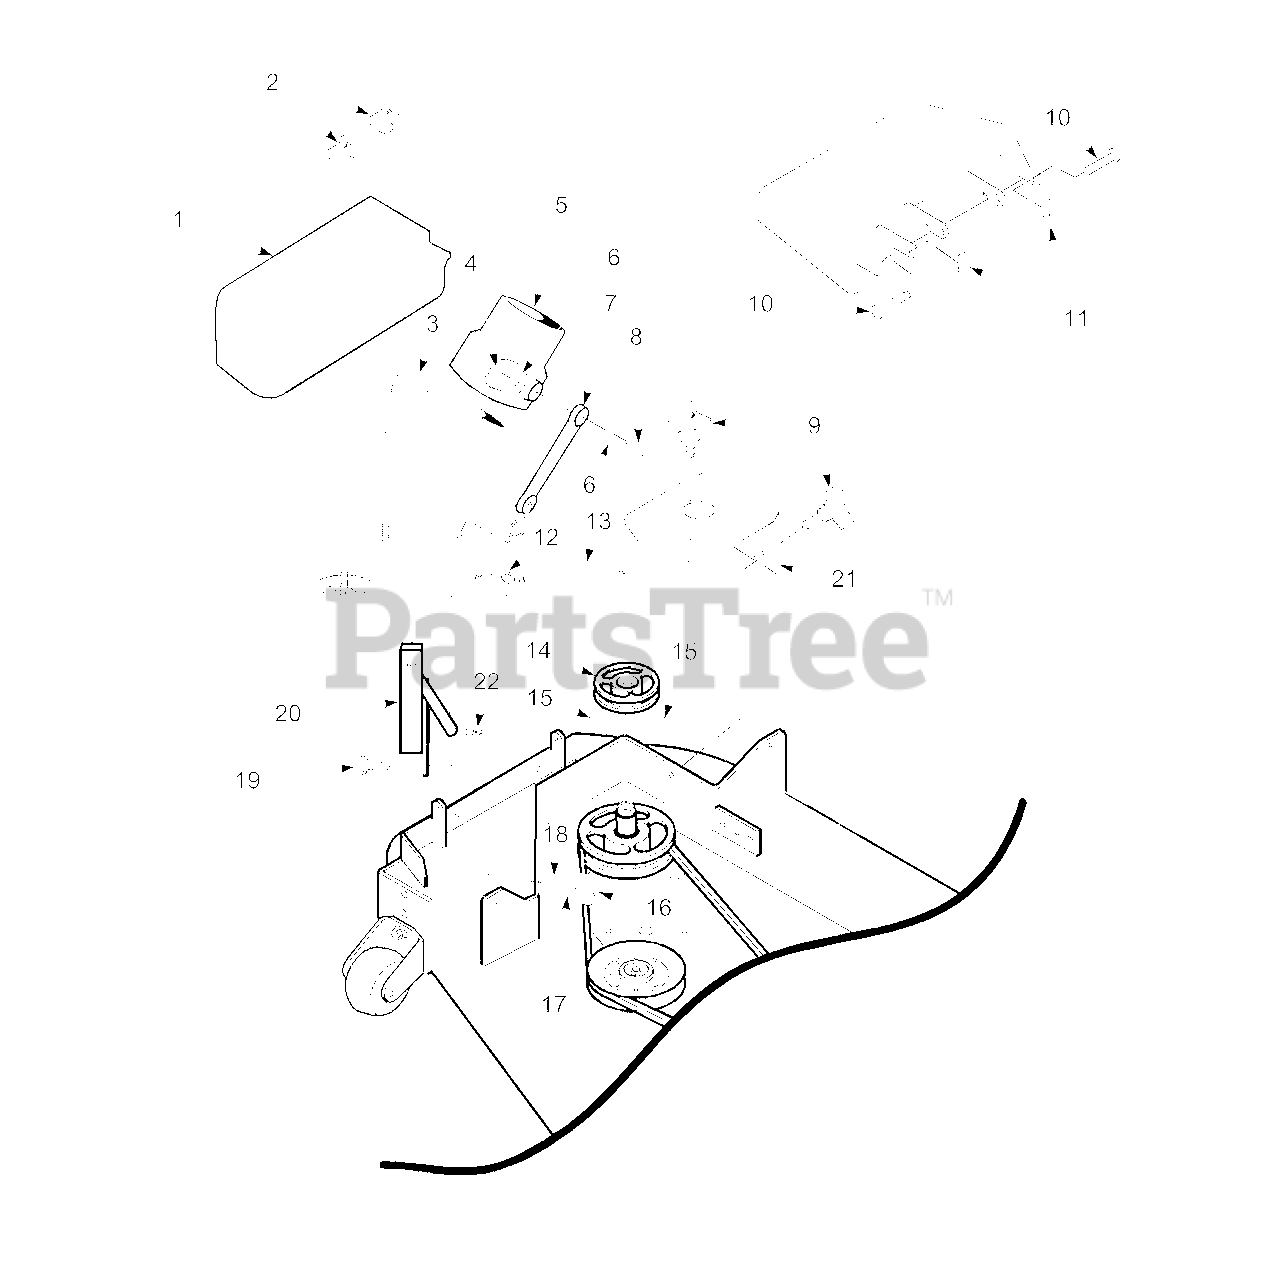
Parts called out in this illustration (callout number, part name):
1	Belt Cover, GC-STC
2	Wingnut, Plastic 3/8 Small
3	Cap, Square Vinyl
4	Nut, Elastic Stop 1/4-20
5	Adapter, Blower GC-STC
6	Flatwasher, 1/4-.312 x .750 x .065
7	Rubber Strap 7-3/4"
8	Bolt, Hex Head 1/4-20 x 1-1/4"
9	Knob W/Stud, 3/8-16 x 1-1/4"
10	Clevis Pin, 5/16 x 1-1/2"
11	Pin, Rue Cotter 5/16 Dia.
12	Pin, Ring 1/2 x 2-1/4"
13	Lanyard
14	Pulley, 3-1/4" for 48" Deck
15	Setscrew, 5/16-18 x 3/8"
16	Nut, Elastic Stop 3/8-16
17	Lockwasher, 3/8"
18	Flatwasher, 3/8-.391 x .938 x .105
19	Bolt, Carr. 3/8-16 x 1-1/4" Grade 5
20	Mounting Post Weldment, Blower
21	Belt Cover
